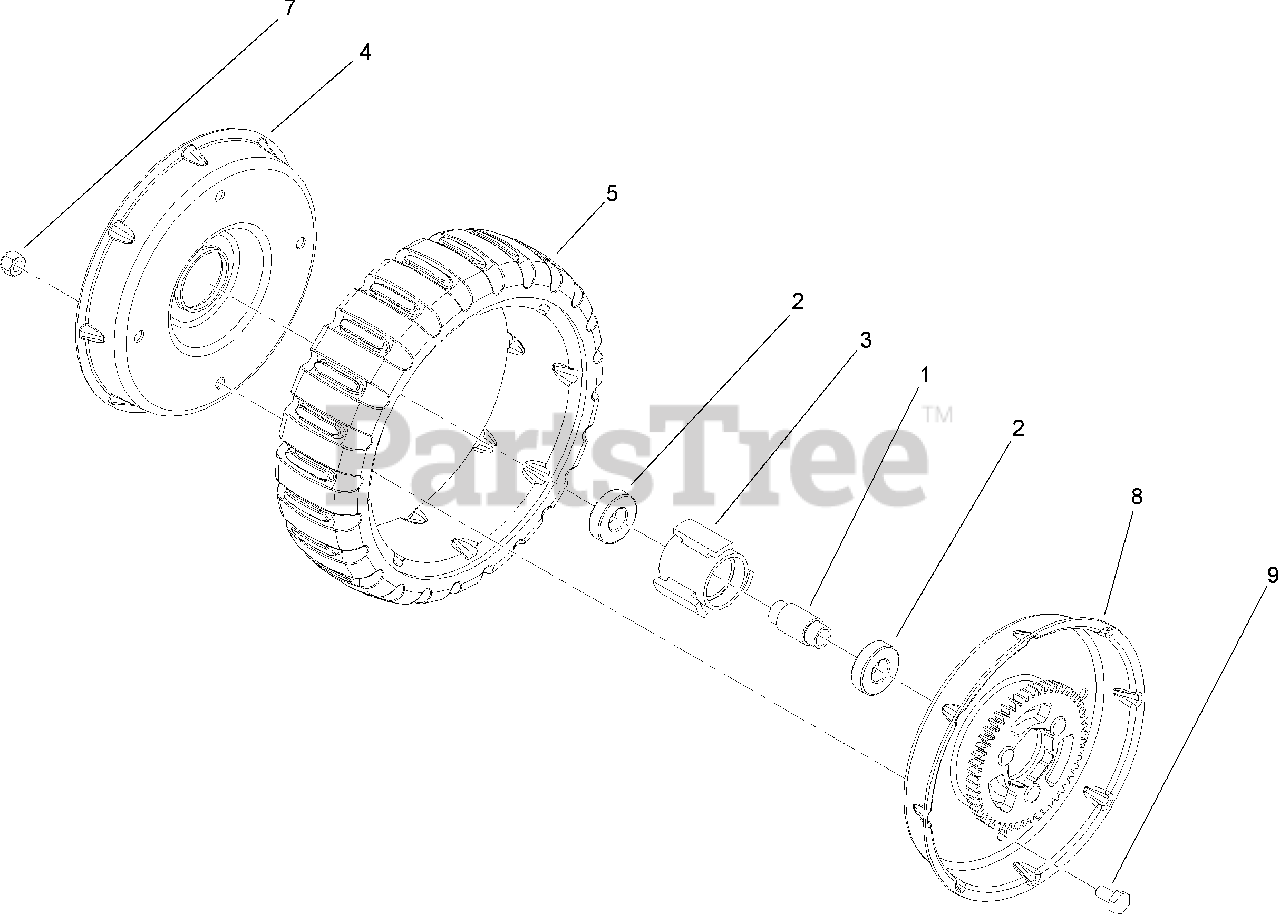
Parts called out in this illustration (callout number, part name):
1	SPACER-BEARING
2	BEARING-WHEEL
3	HUB-BEARING
4	WHEEL HALF
5	TIRE-8 INCH
7	NUT-LOCK, NI
8	HUB AND GEAR ASM
9	SCREW-HH
